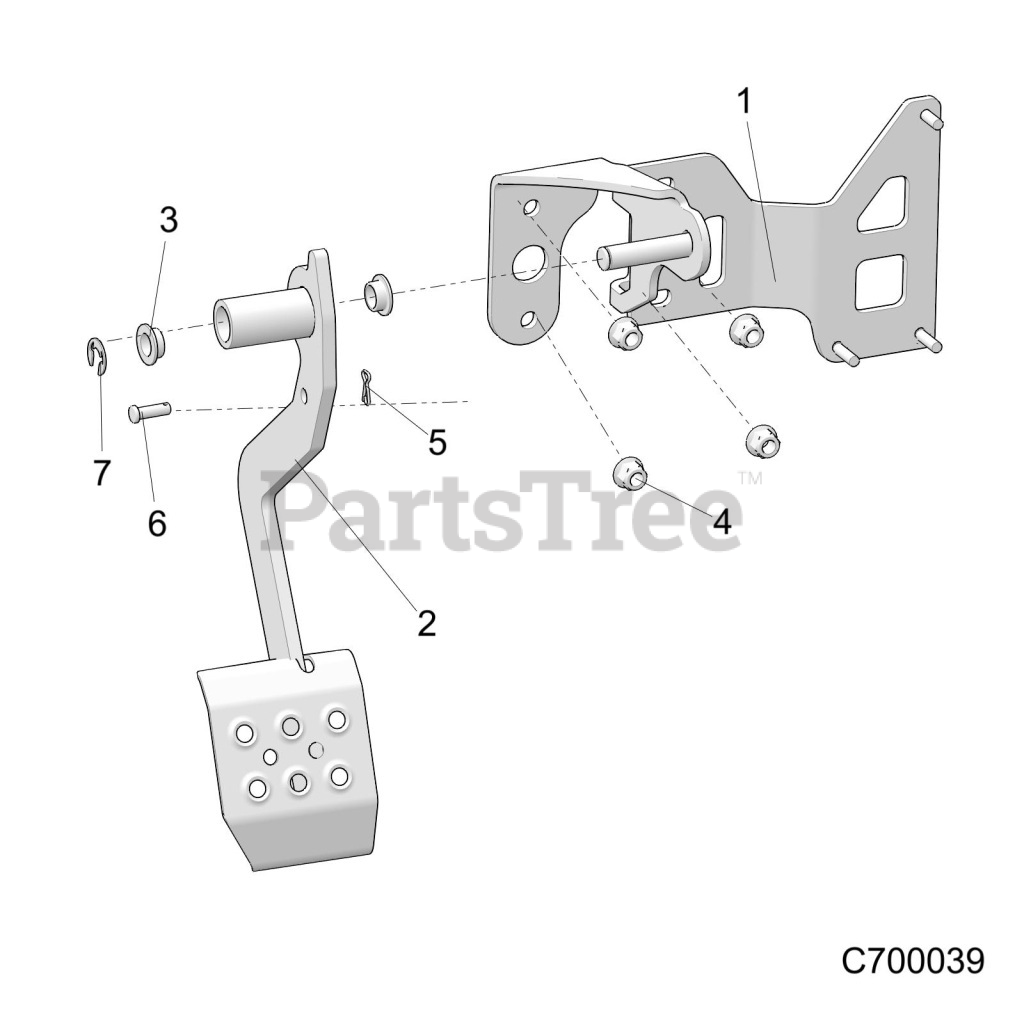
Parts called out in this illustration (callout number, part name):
1	WELD-PEDAL MOUNT,BLK
2	PEDAL, BRAKE, MATTE BLACK
3	BUSHING-PEDAL PIVOT
4	NUT-M8X1.25,FLG,NYLOC-OLIVE D
5	PIN-CLIP,14MM
6	PIN-CLEVIS, 1/4 X 3/4 -Y
